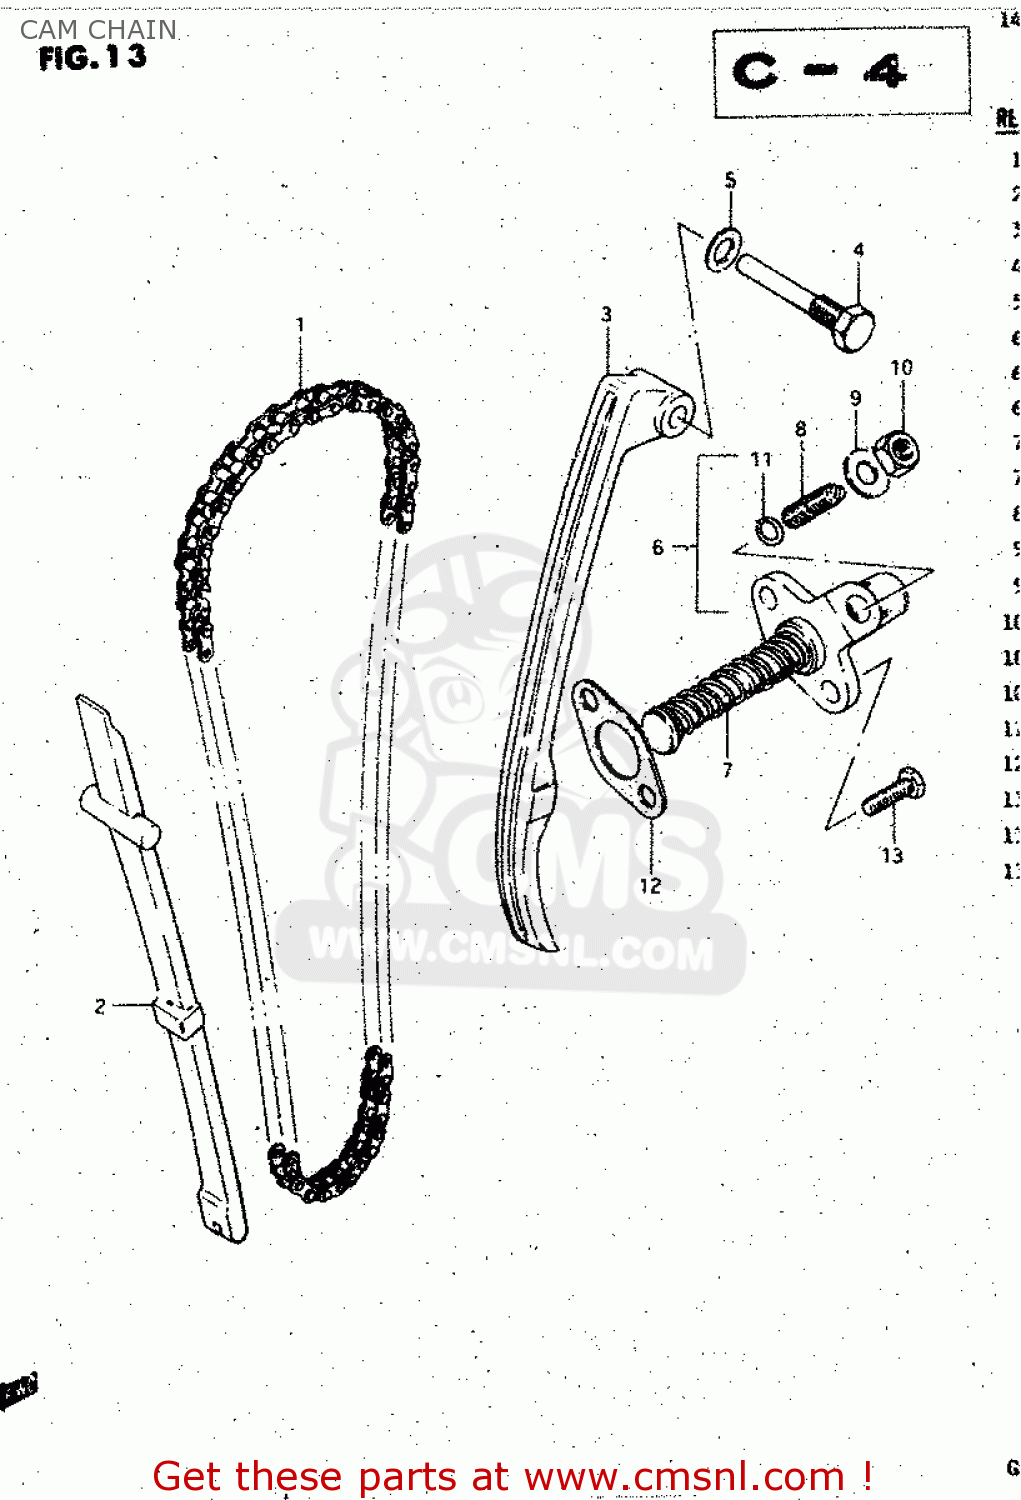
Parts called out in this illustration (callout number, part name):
1	CHAIN,CAMSHAFT DRIVE
2	GUIDE,CAM CHAIN
3	TENSIONER,CAM CHAIN
4	BOLT,CAM CHAIN TENSIONER
5	GASKET 8.2X14X1 (NAS)
6	ADJUSTER ASSEMBLY,TENSIONER
7	SPRING
8	SCREW
9	WASHER
10	NUT
11	O RING(D:1.9,ID:5.7)
12	GASKET,TENSIONER ADJUSTER (NAS)
13	BOLT
